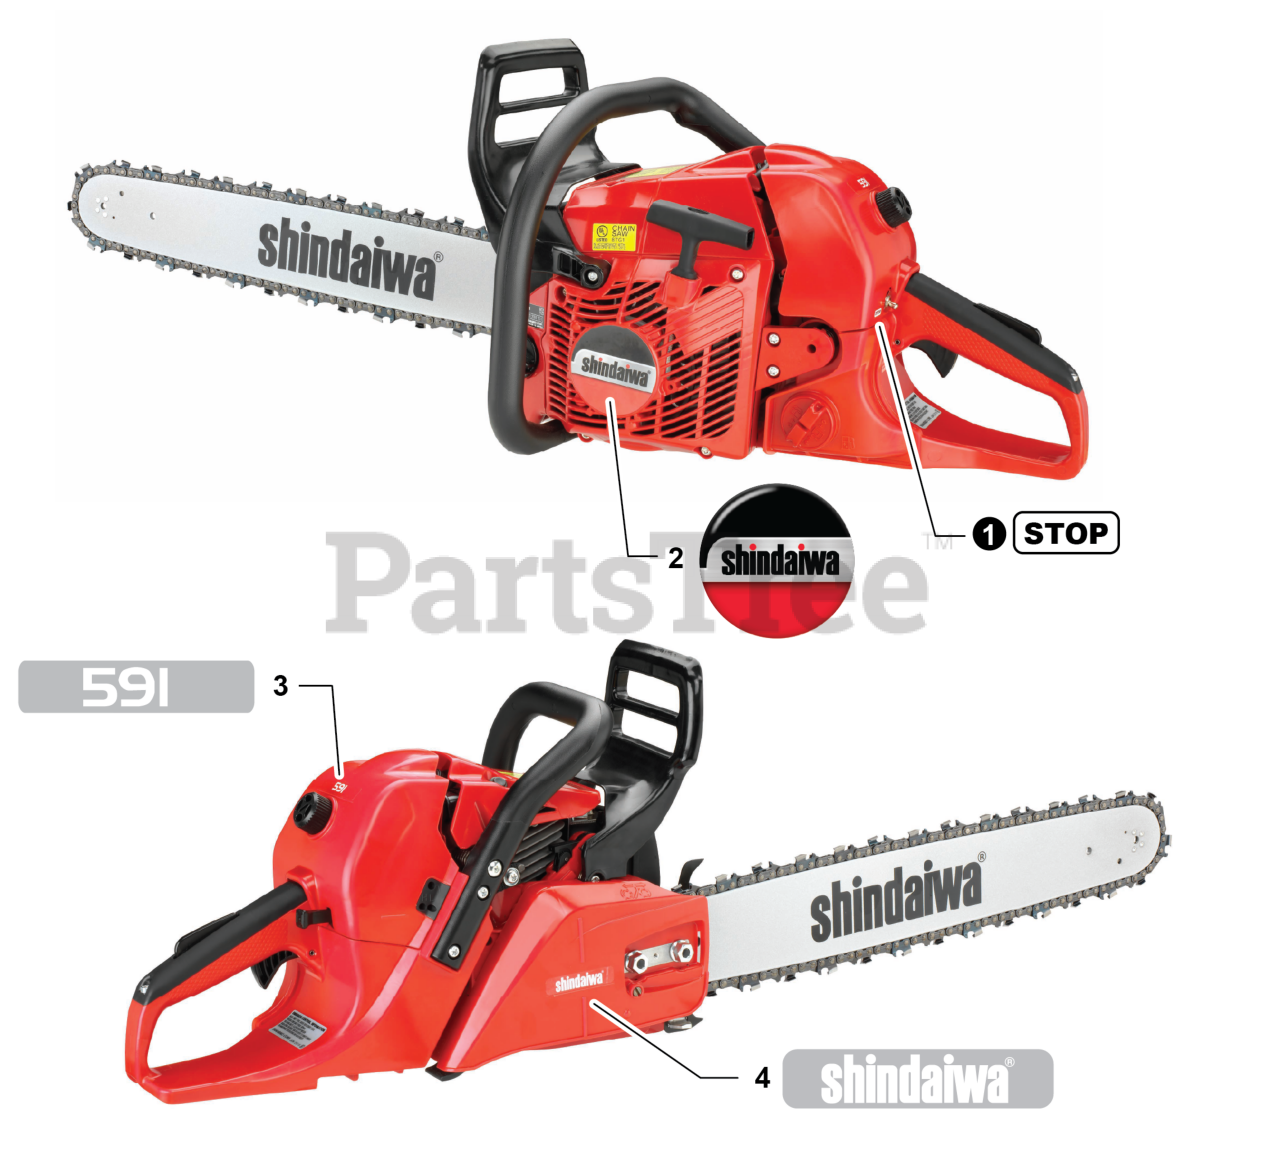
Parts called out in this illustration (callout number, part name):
1	LABEL - STOP
2	LABEL - STARTER - SHINDAIWA
3	LABEL - MODEL 591
4	LABEL - SHINDAIWA
